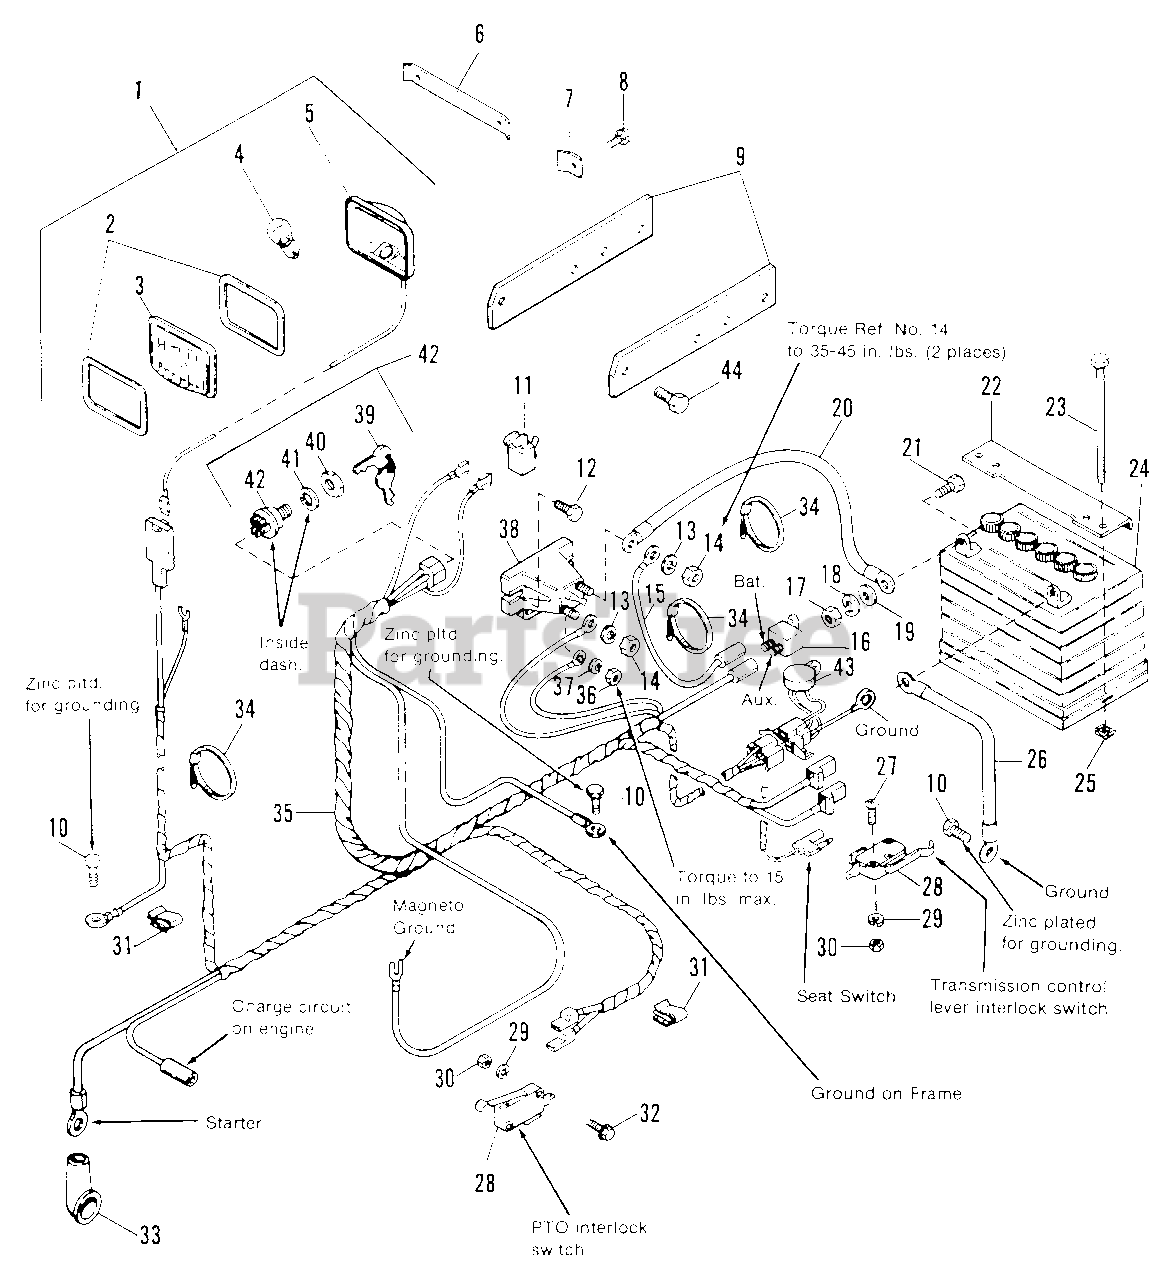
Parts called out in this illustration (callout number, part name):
1	LIGHT ASSY. (Incl. Ref. No. 2, 3, 4 & 5)
3	LENS, Plastic, Clear
5	REFLECTOR ASSY.
6	CLIP, Headlight Center
7	CLi P. Headlight, Side
8	SCREW, Plastite #10-14 x 1-1/2
9	BRACE, Shift Panel
10	SCREW, Taptite, 1/4-20 x 3/8 (Zinc pltd.)
11	SWITCH ASSY.
12	SCREW, Taptite, 1/4-20 x 3/4 (Zinc pltd.)
13	LOCKWASHER, 5/16
14	NUT, Hex, 5/16-24
16	CIRCUIT BREAKER
17	NUT, Hex, 1/4-20
18	LOCKWASHER, 1/4
19	WASHER, 1/4
21	CAPSCREW, Hex, 1/4-20 x 3/4
22	CLAMP, Battery
23	CAPSCREW, Hex, 1/4-20 x 7
24	BATTERY SERVICE KIT, 39 Amp.
25	NUT, Retainer, 1/4-20
27	SCREW, Rd. Hd., Phil. #5-40 x 3/4
28	SWITCH, Interlock
29	LOCKWASHER, #5
30	NUT, Hex, 5-40
31	CLIP, Wire
32	SCREW, Taptitie, 5-40 x 3/4
33	COVER, Terminal
34	TIE, Selflocking
35	HARNESS, Wiring (1691029 only)
35	HARNESS, Wiring (1691271 & 1691325 only)
36	NUT, Hex, 10-32
37	LOCKWASHER, 10
38	SOLENOID
39	KEYS, Set of 2
40	NUT, 5/8-32
41	LOCKWASHER, Int. Tooth, 5/8
42	SWITCH, Ignition (Incl. Ref. No. 39, 40 & 41)
43	MODULE, DSI Interlock
44	SCREW, Taptite, 1/4-20 x 3/8
